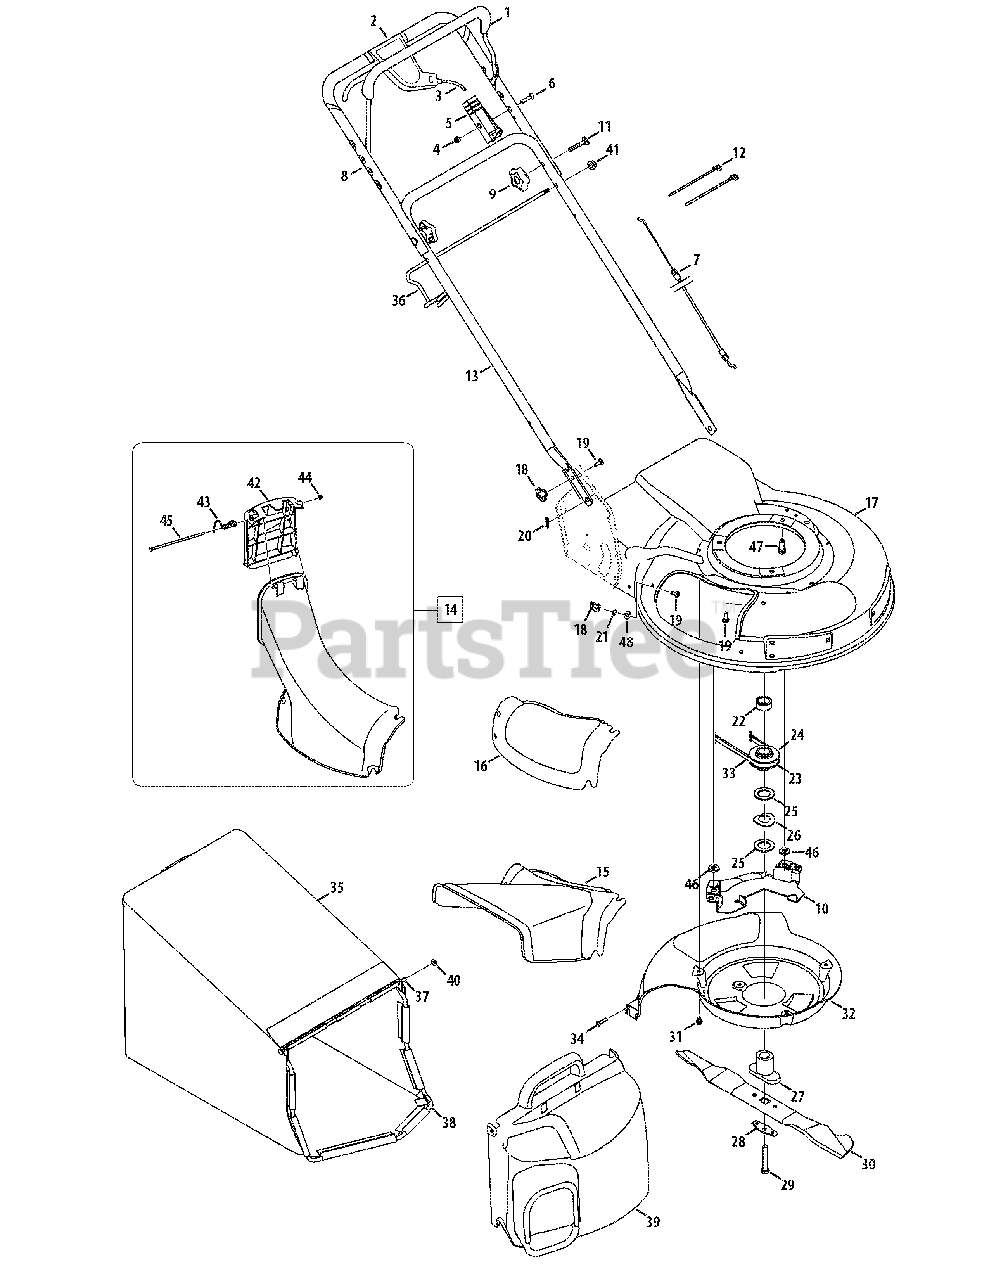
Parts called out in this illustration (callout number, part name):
2	Control Lever Assembly
3	Drive Cable 51"
4	Top Lock Nut 1/4-20
5	Control Housing
6	Oval C-Sunk Screw
7	Control Cable 47"
9	Star Knob
10	Belt Keeper
11	Carriage Bolt 5/16-18 x 2.0
12	Cable Tie
14	Chute Assembly
15	Side-Discharge Chute
16	Mulch Cover
19	Carriage Bolt 1/4-20 x .75"
20	Cotter Pin
21	Push Nut .25 x ID x .50 OD
22	Slv. Spcr., 25mm x 1.375 x .440
23	Half Pulley: Key 25mm x 2.62 OD
24	Half Pulley: Upper 25mm x 2.62
25	Flat Washer 1.031 x 1.620 x .095
26	Wave Washer, 1.5 x 1.0 x .029
27	Blade Adapter
28	Blade Bell Support
29	Hex Bolt 3/8-24 x 2.5
30	21" Mulching Blade
31	Screw 1/4-20 x 3.75
32	Baffle
33	Belt 3/8 x 39.24
34	HL Screw 1/4-15 x .75
35	Grass Catcher
37	Pivot Rod
39	Grass Bag Cover
40	Cap Nut
41	Hex Nut 5/16-18
42	Chute Door
43	Torsion Spring
44	Push Cap
45	Pivot Rod
46	Washer, Flat, .407 x .812 x .135
47	Sems Screw 3/8-16 x 1.00
48	Washer, Flat, .260 x .720 x .060
